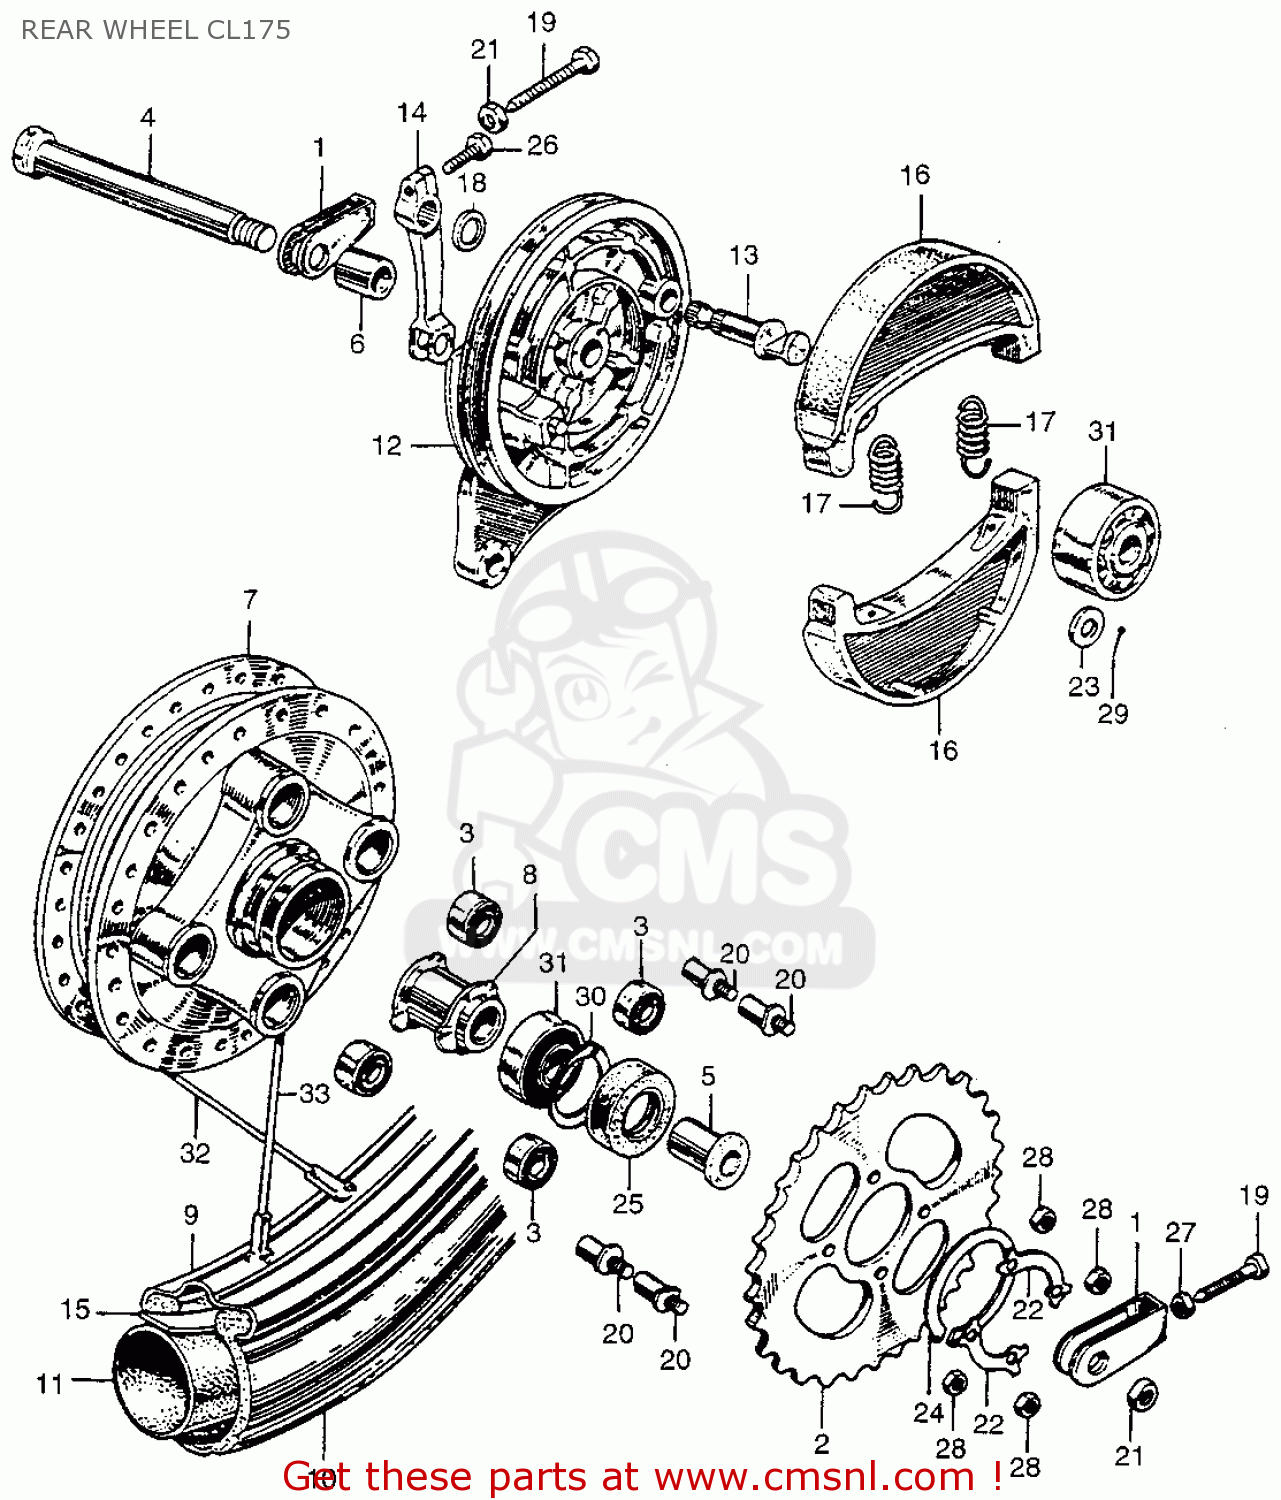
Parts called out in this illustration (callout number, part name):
1	ADJUSTER CHAIN
2	SPROCKET 40T
3	BUSH,REAR.DAMPER
4	AXLE,REAR WHEEL
5	COLLAR WHEEL
6	COLLAR, PANEL
7	HUB, RR. WHEEL
8	COLLAR,REAR,AXLE
9	RIM, REAR WHEEL
10	TIRE REAR 300X18
11	TUBE,TIRE
12	PANEL, RR. BRAKE
13	CAM REAR BRAKE
14	ARM,REAR BRAKE
15	FLAP TIRE
16	SHOE,RR.BRAKE (MCA)
17	SPRING,BRAKE SHOE
18	DUST-SEAL, BRAKE
19	BOLT,CHAIN ADJUST
20	BOLT,DRIVEN
21	NUT, RR. AXLE
22	WASHER,TONGUED
23	WASHER, HANDLE
24	CIRCLIP, 58M/M
25	DUST SEAL WHEEL
26	BOLT,HEX 6X20
27	NUT HEX 6MM
28	NUT HEX 6MM
29	PIN,SPLIT, 2.0
30	CIRCLIP IN 47MM
31	B/BRG RAD N/COM
32	SPOKE,9X163.5
33	SPOKE,9X162.5
